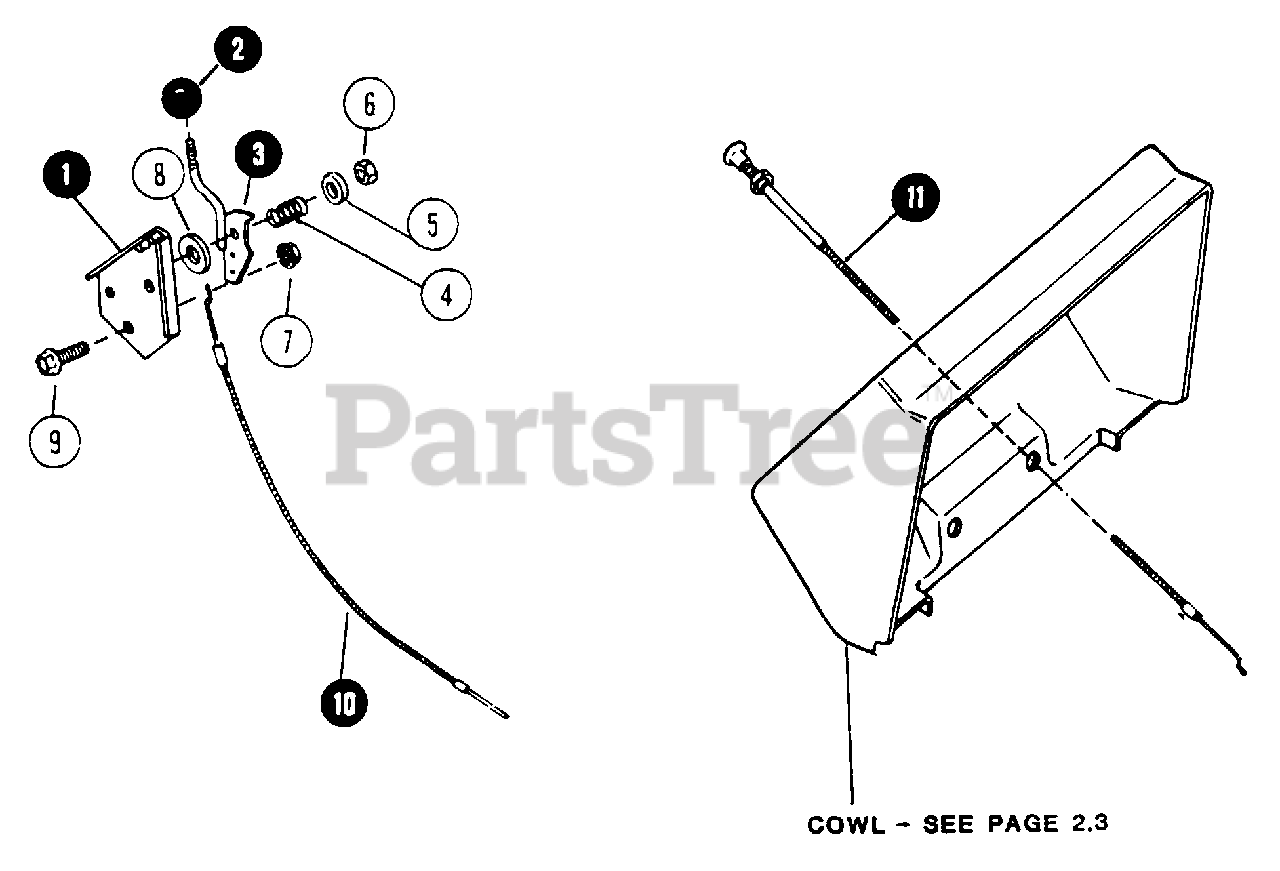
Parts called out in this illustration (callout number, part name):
1	BRACKET, THROTTLE CONTROL
2	KNOB, THROTTLE ARM
3	ARM, THROTTLE CONTROL
4	SPRING, ARM TENSION
5	WASHER, 5/16 FLAT
6	NUT, 5/16C HEX LOCK
7	NUT, 3/8C HEX FLANGE LOCK
8	WASHER, FRICTION
9	BOLT, 3/8C x 3/4 HEX
10	CABLE, THROTTLE CONTROL
11	CABLE, CHOKE CONTROL
